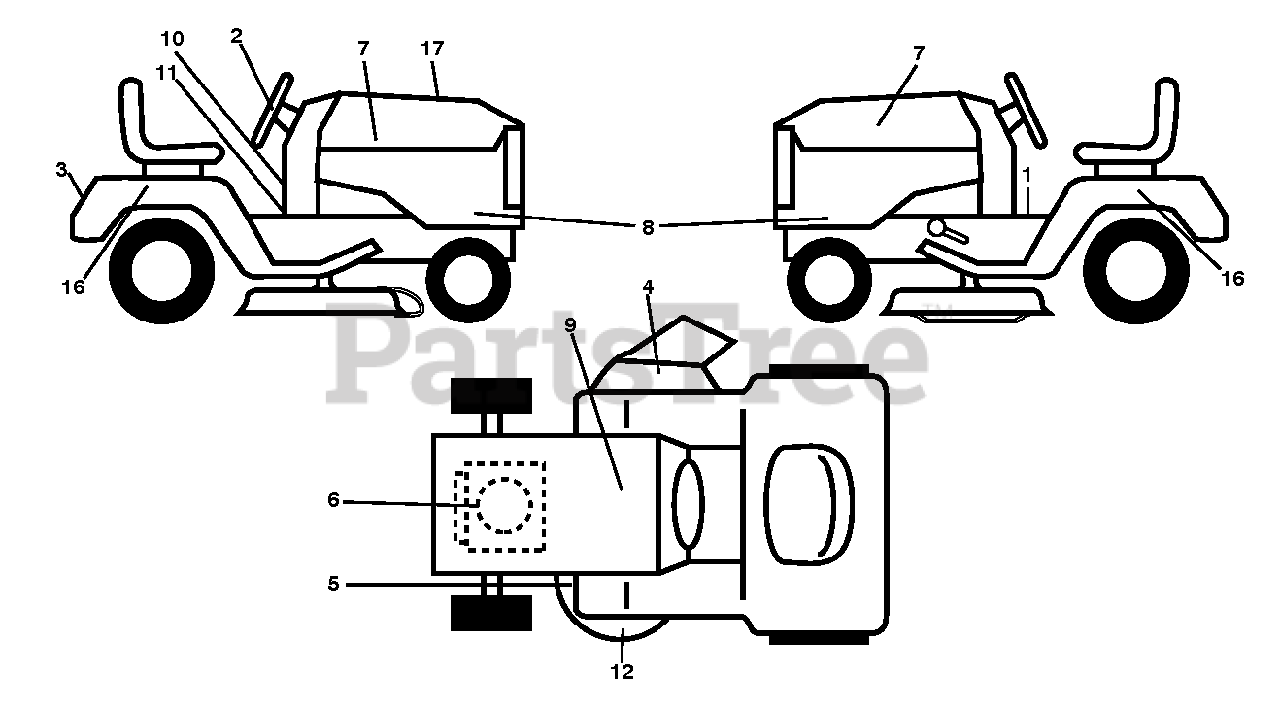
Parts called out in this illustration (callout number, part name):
1	DECAL.FENDER.WARNING.ENGLISH
2	Decal, Steering Wheel STDXXSQ PPRO 2015
3	DECAL.REARFNDR.POULAN PRO.2015
4	DECAL, DECK DEFLECTOR, WARNING
5	DECAL.V-BELT.SCH.42/46"MEC/ELE
6	DECAL.ENG.BS.18INTK.DOM.381706
7	DECAL.POULAN PRO.2015
8	DECAL.SDPNL.PB20A46.BLK.PPRO
9	DECAL BTRY SYMBOLS
10	DECAL.PB20A46.HOOD.POP
11	DECAL, WARNING SPARK ARRESTOR
12	DECAL.PPRO.10YRDECKWAR.POP
